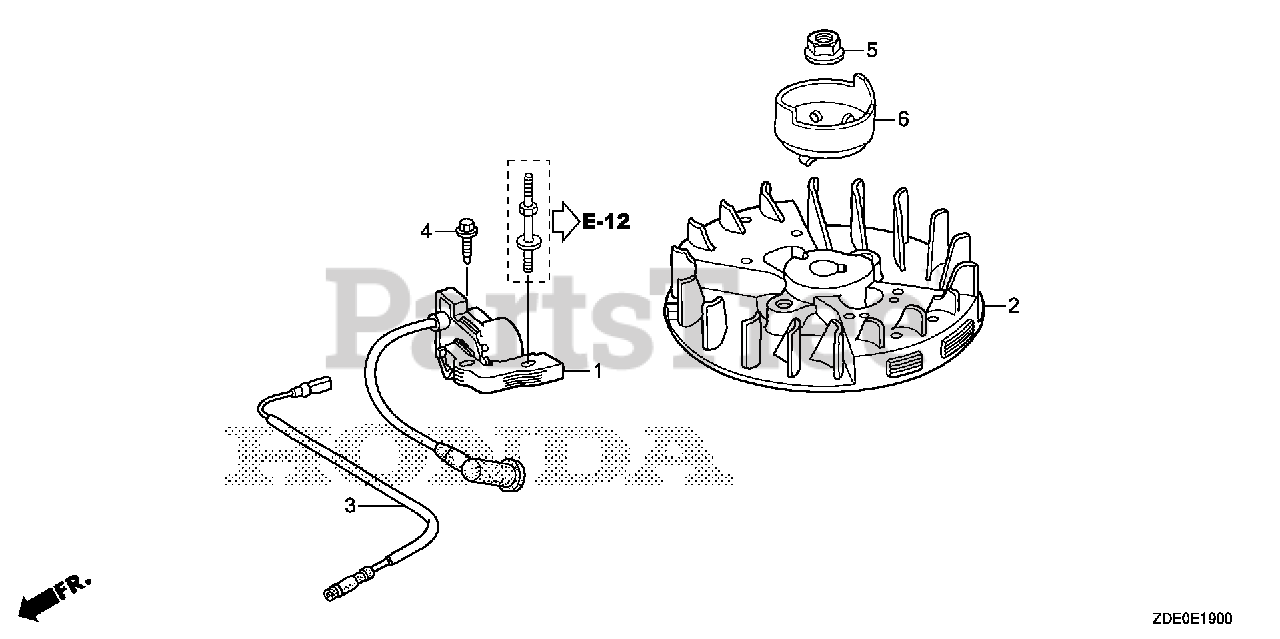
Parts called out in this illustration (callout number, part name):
1	COIL ASSY., IGNITION
3	WIRE, STOP SWITCH
4	BOLT, FLANGE (5X20)
5	NUT, FLANGE (10MM)
6	PULLEY, RECOIL STARTER
